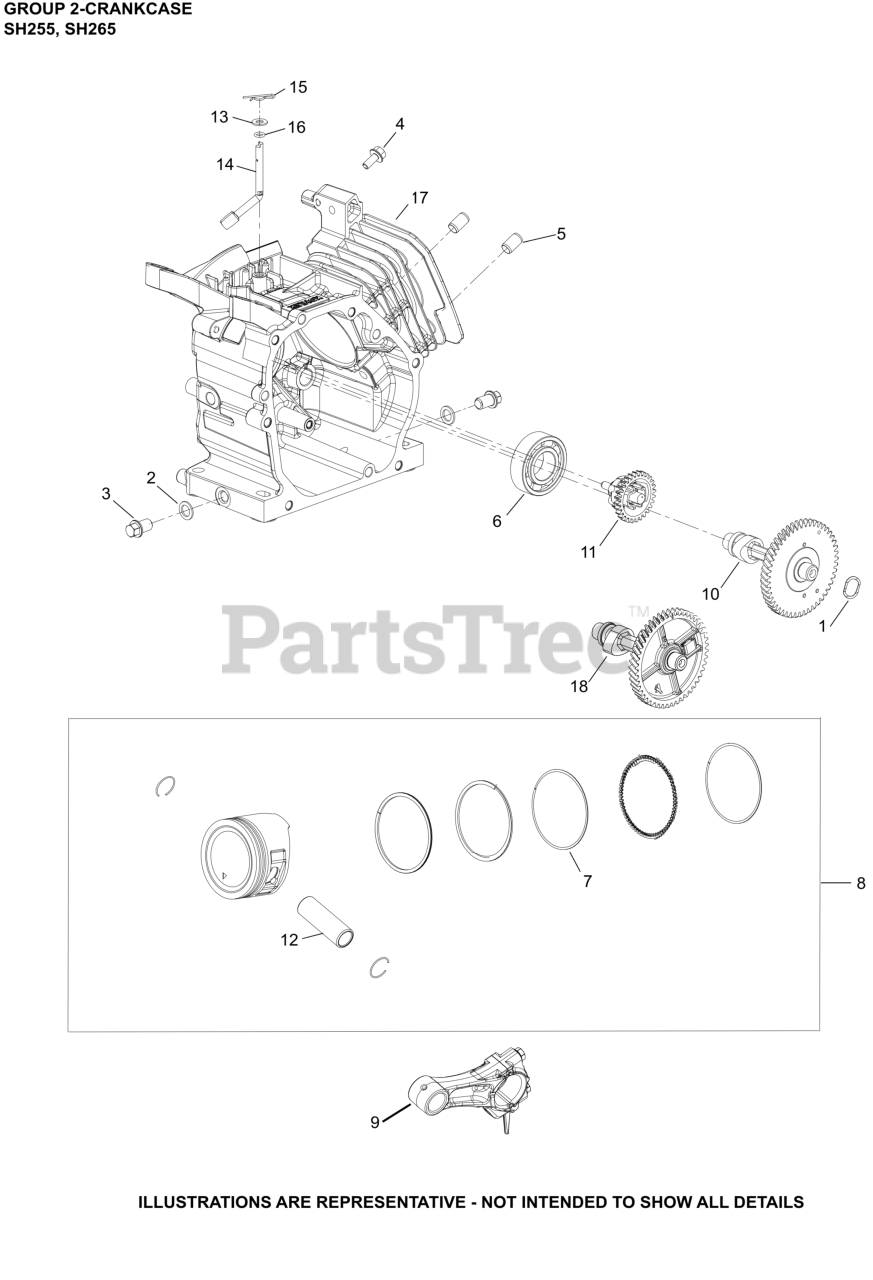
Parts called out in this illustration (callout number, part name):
2	WASHER, DRAIN PLUG
3	KIT, DRAIN PLUG
5	DOWEL, CYLINDER HEAD
6	BEARING, BALL
8	KIT, PISTON (STD)
9	ROD, CONNECTING ASSEMBLY
11	GOVERNOR ASSEMBLY
12	PIN, PISTON
13	WASHER, FLAT (DIA 13mm O.D.)
14	CROSS SHAFT
15	CLIP, GOVERNOR SHAFT
17	CRANKCASE
18	CAMSHAFT, ASSEMBLY
